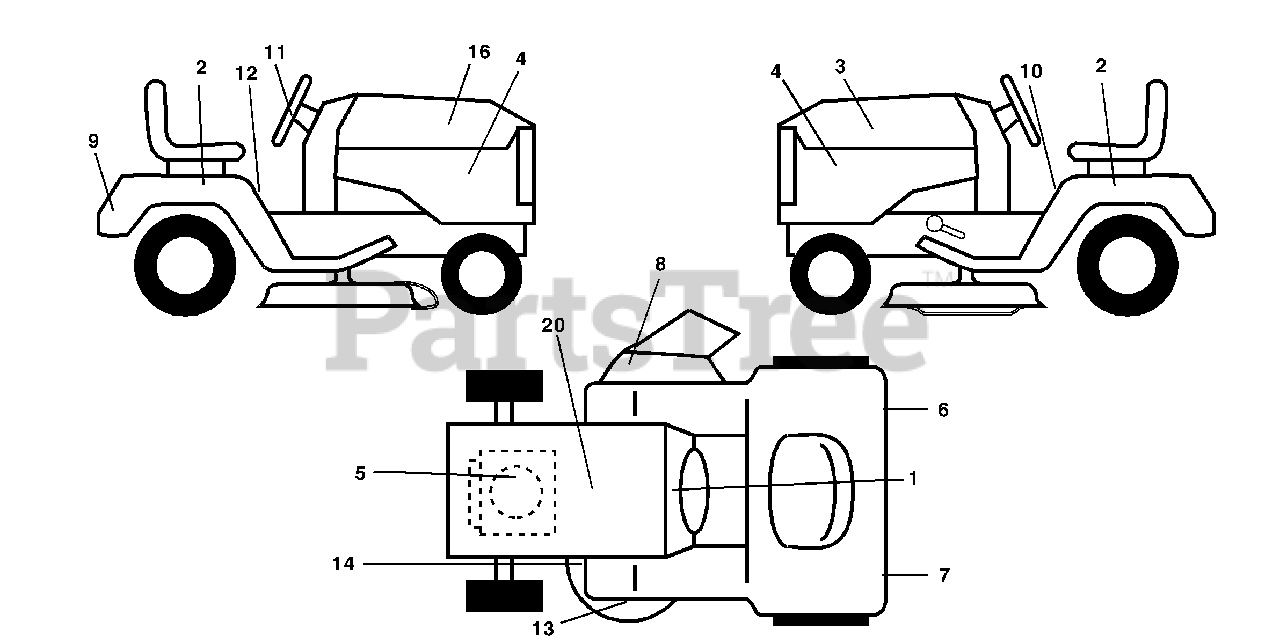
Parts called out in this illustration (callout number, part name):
1	Decal Dash
2	Decal Fender Auto
3	Decal Hood LH
4	Decal Side Panel
5	Decal HP Engine
6	Decal Reflector Rh
7	Decal Reflector Lh
8	Decal Warning Mower
9	Decal Fender Logo
10	Decal Fender Danger E/F
11	Decal Ins Strg Whl
12	Decal Fender Oper Cruise
13	Decal Deck Caution
14	Decal V-Belt Schematic
16	Decal Hood Rh
20	Decal Bat Dan/Psn
